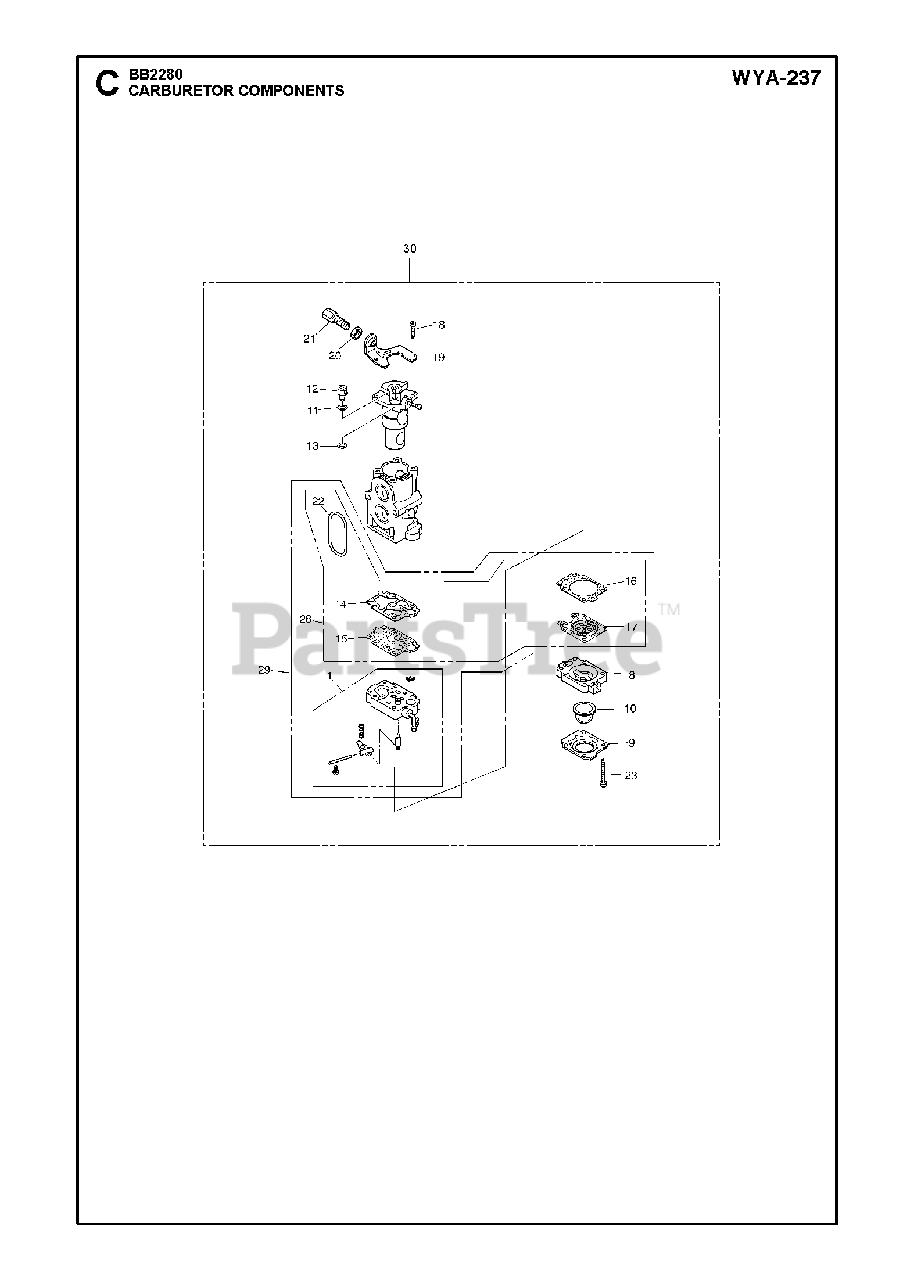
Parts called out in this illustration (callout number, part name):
1	RP_BODY-A-PUMP
8	BODY
9	COVER
10	PUMP
11	WASHER
12	SWIVEL
13	RING
14	GASKET
15	DIAPHRAGM
16	GASKET
17	DIAPHRAGM
18	SCREW
19	BRACKET
20	NUT
21	ADJUSTER
22	RING
23	SCREW
28	GASKET KIT
29	REBUILD KIT
30	Carburetor Assembly
